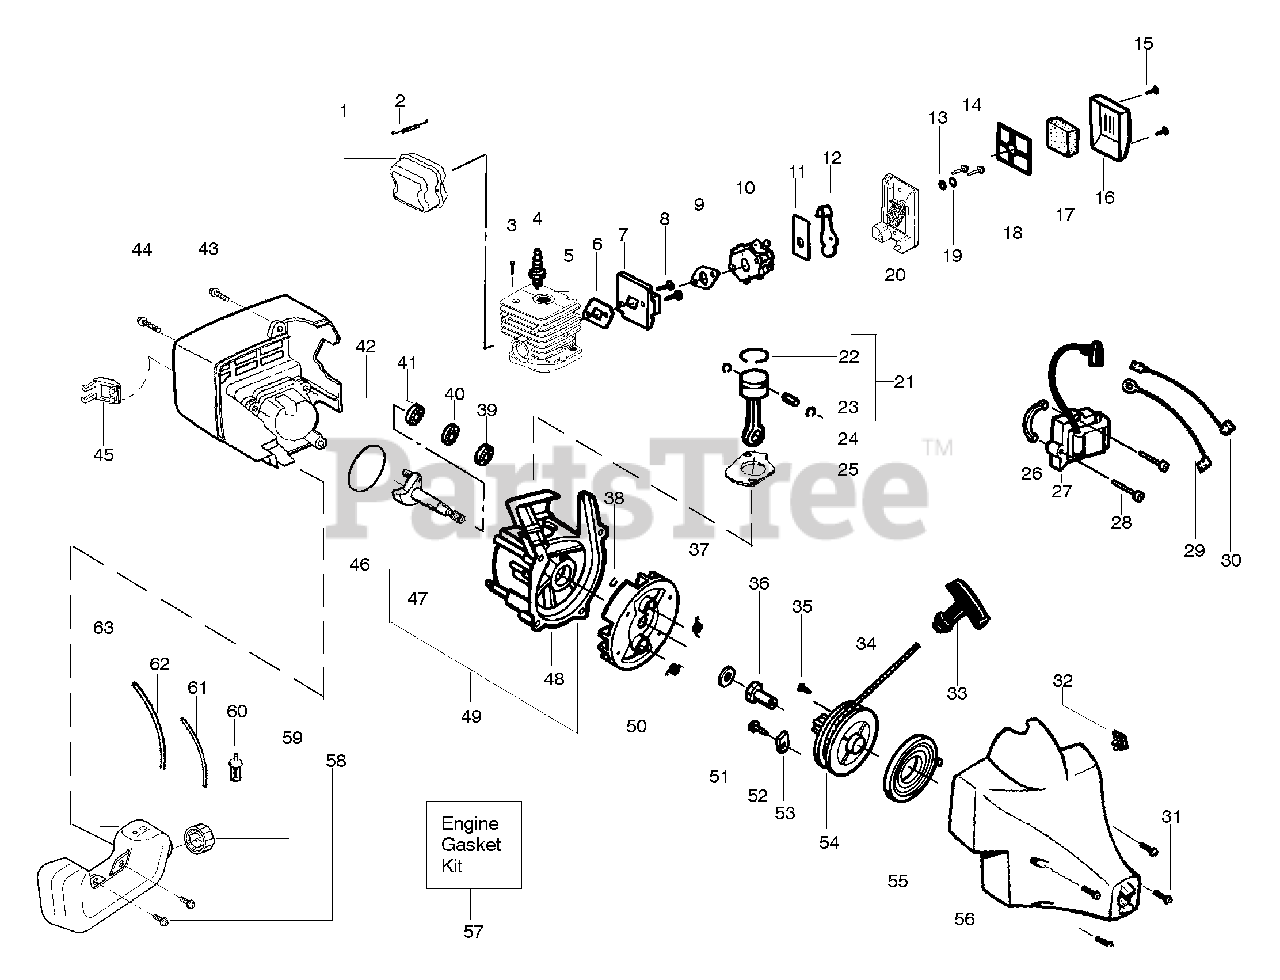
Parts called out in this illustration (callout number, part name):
1	Kit - Muffler
2	Muffler Spring
3	Screw-Cylinder
4	Spark Plug (RCJ 6Y)
5	Kit - Cylinder
6	Gasket-Cyl/Carb.(kit)
7	Adaptor-carb.
9	Gasket-Carb.(kit)
10	Kit - Carburetor Ass'y (Wa-226)
10	Kit - Carburetor Ass'y (C1U-W7)
10	Kit - Carburetor Ass'y (WT-631)
11	Plate-Choke Mounting
12	Lever-Choke
16	Cover-Air Box
17	Foam-Air Filter
18	Plate-Air Filter Support
19	Spacer-Choke
21	Kit - Piston
22	Piston Ring
23	Retainer-Piston Pin
24	Assy-Connecting Rod
25	Gasket-Cylinder(kit)
26	Spacer-Module
27	Ignition Module
29	Assy-Ground Wire
30	Assy-Leadwire
31	Screw
32	Kit-Switch
33	Handle-Starter
34	Kit - Rope
36	Coupling-Drive
37	Spring-Starter Dog
38	Retain. Ring-C'shaft
39	Bearing-Outer
40	Seal-C'case
41	Bearing-Inner
44	Screw
45	Guard-Muffler
46	O-Ring-C'case(kit)
47	Assy-Crankshaft
48	Assy-Crankcase
49	Assy-C'case & C'shaft
50	Assy-Flywheel
51	Washer-Flat
53	Retainer-Can
54	Kit-Starter Pulley
55	Spring-Starter
56	Assy-Fan Housing
57	Kit-Engine Gasket
58	Retainer-Tank
59	Assy-Fuel Cap
60	Assy-Fuel Pickup
61	Kit-Fuel Line
62	Kit-Fuel Line
63	Assy-Fuel Tank
